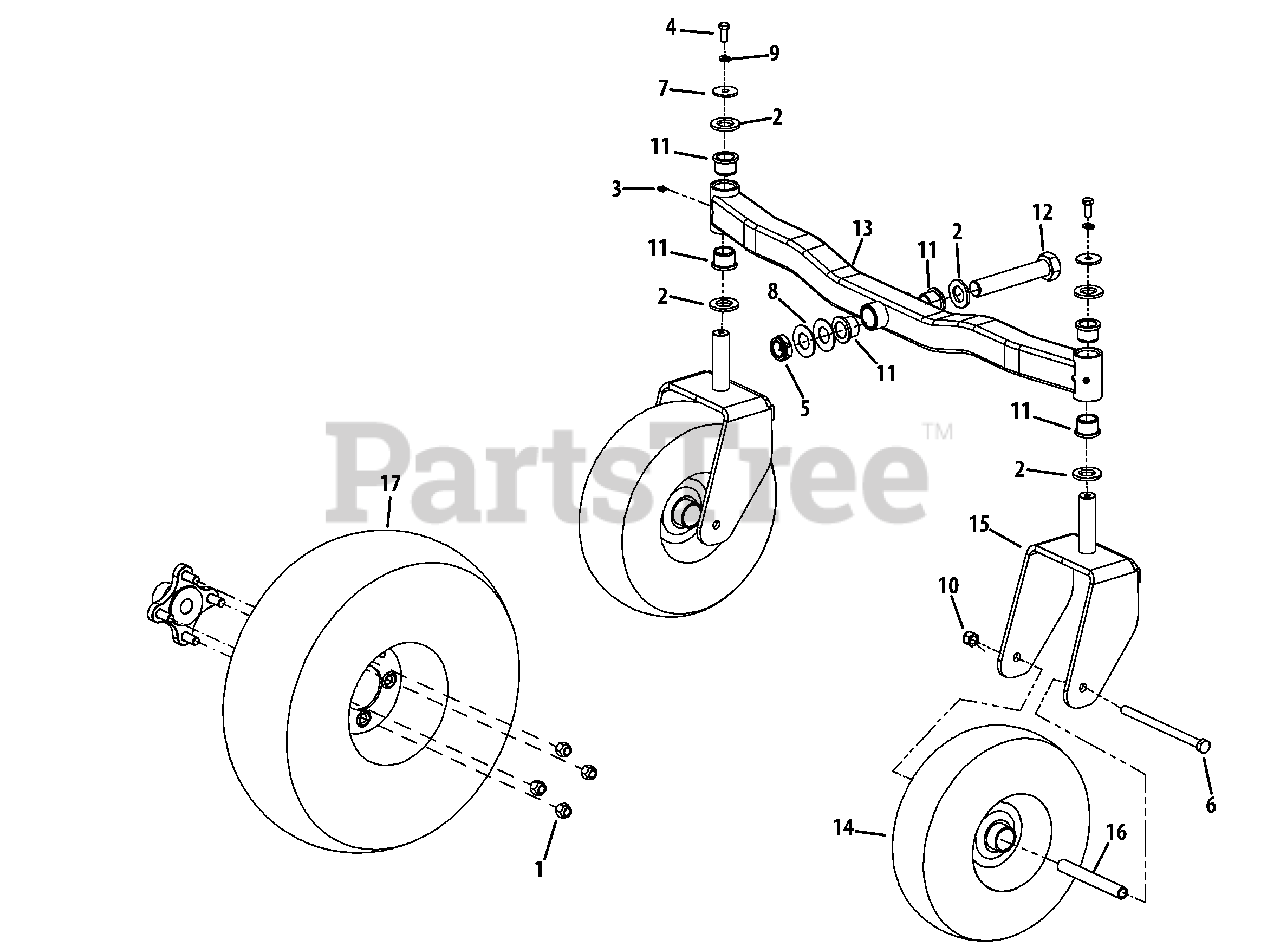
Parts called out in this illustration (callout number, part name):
1	Lug Nut, 1/2-20
2	Washer, Flat, 1.01 x 1.75 x .172
3	Grease Fitting, 1/4-28
4	Hex Screw, 3/8-16 x .880
5	Jam Nut, 1-14
6	Hex Screw, 1/2-20 x 7.50
7	Flat Washer, .390 x 1.50 x .134
8	Washer, 1.00 x :2.00 x .075
9	Lock Washer, 3/8
10	Nylock Nut, 1/2-20
11	Flange Bearing, 1.001 x 1.25
12	Hex Screw, 1-14 x 5.5
13	Front Axle Weldment
14	Wheel Assembly, 13 x 5-6
15	Castor Wheel Mount Bracket Assy.
16	Spacer, .51 x .75 x 5.825
17	Wheel Assy., 20 x 8-10 (48" Deck)
